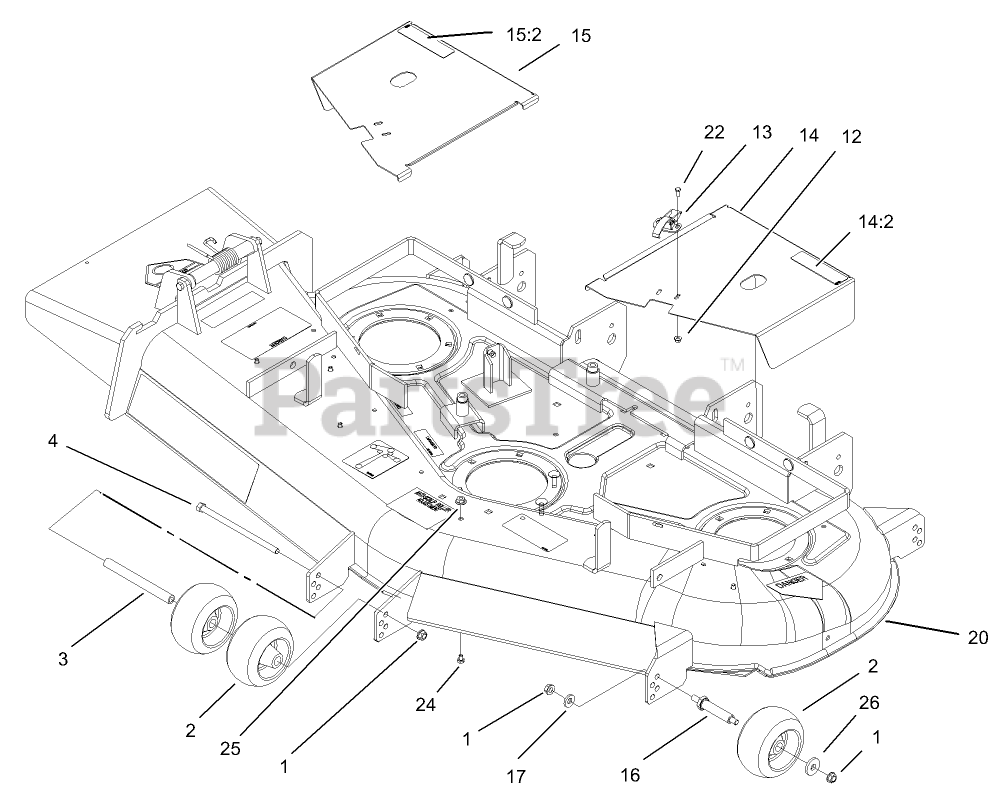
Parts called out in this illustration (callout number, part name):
1	NUT-HHF, WHIZ
2	WHEEL-GAGE
3	SPACER-WHEEL
4	SCREW-HH
12	NUT-LOCK, FLANGE
13	CLAMP-SLOTTED
14	LH COVER ASM
14:2	DECAL-DANGER
15	RH COVER ASM
15:2	DECAL-DANGER
16	SPACER
17	WASHER-BELLEVILLE
20	Deck ASM
22	SCREW-HWH
24	SCREW-HH
25	NUT-HF
26	WASHER
